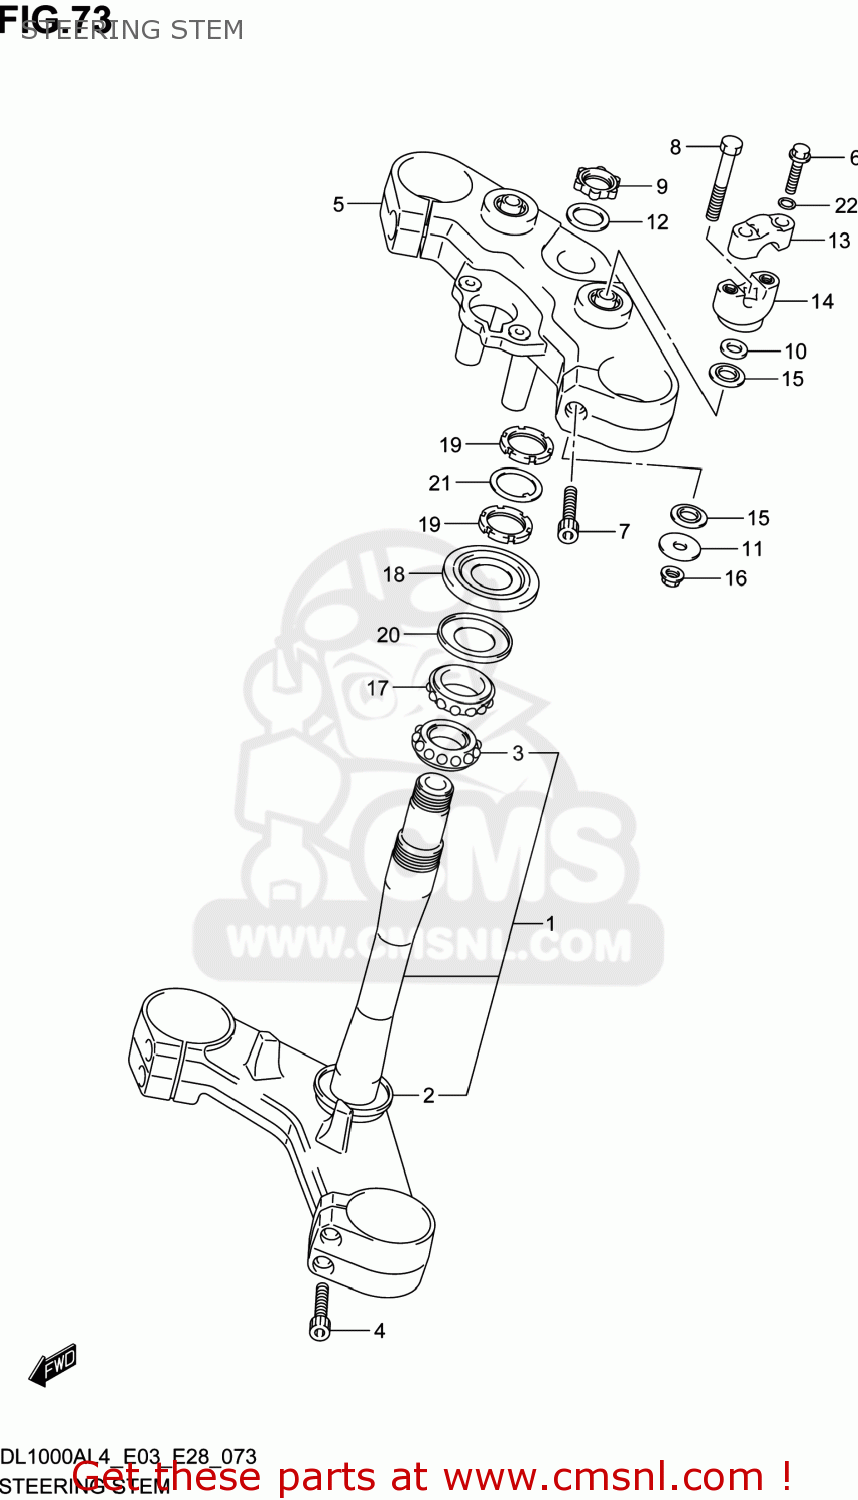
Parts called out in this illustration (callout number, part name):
1	BRACKET,UNDER
2	SEAL,STEERING LWR
3	BEARING(30X55X17)
4	BOLT
5	BRACKET,UPPER(BLACK)
6	BOLT
7	BOLT
8	BOLT
9	NUT
10	WASHER
11	WASHER
12	WASHER
13	HOLDER,HANDLE UPPER(BLACK)
14	HOLDER,HANDLE LOWER(BLACK)
15	RUBBER,HANDLE HOLDER
16	NUT
17	BEARING(30X55X17)
18	COVER,STEERING UPR
19	NUT,STEERING STEM
20	SEAL,STEERING LWR
21	WASHER,STEERING STEM
22	WASHER
